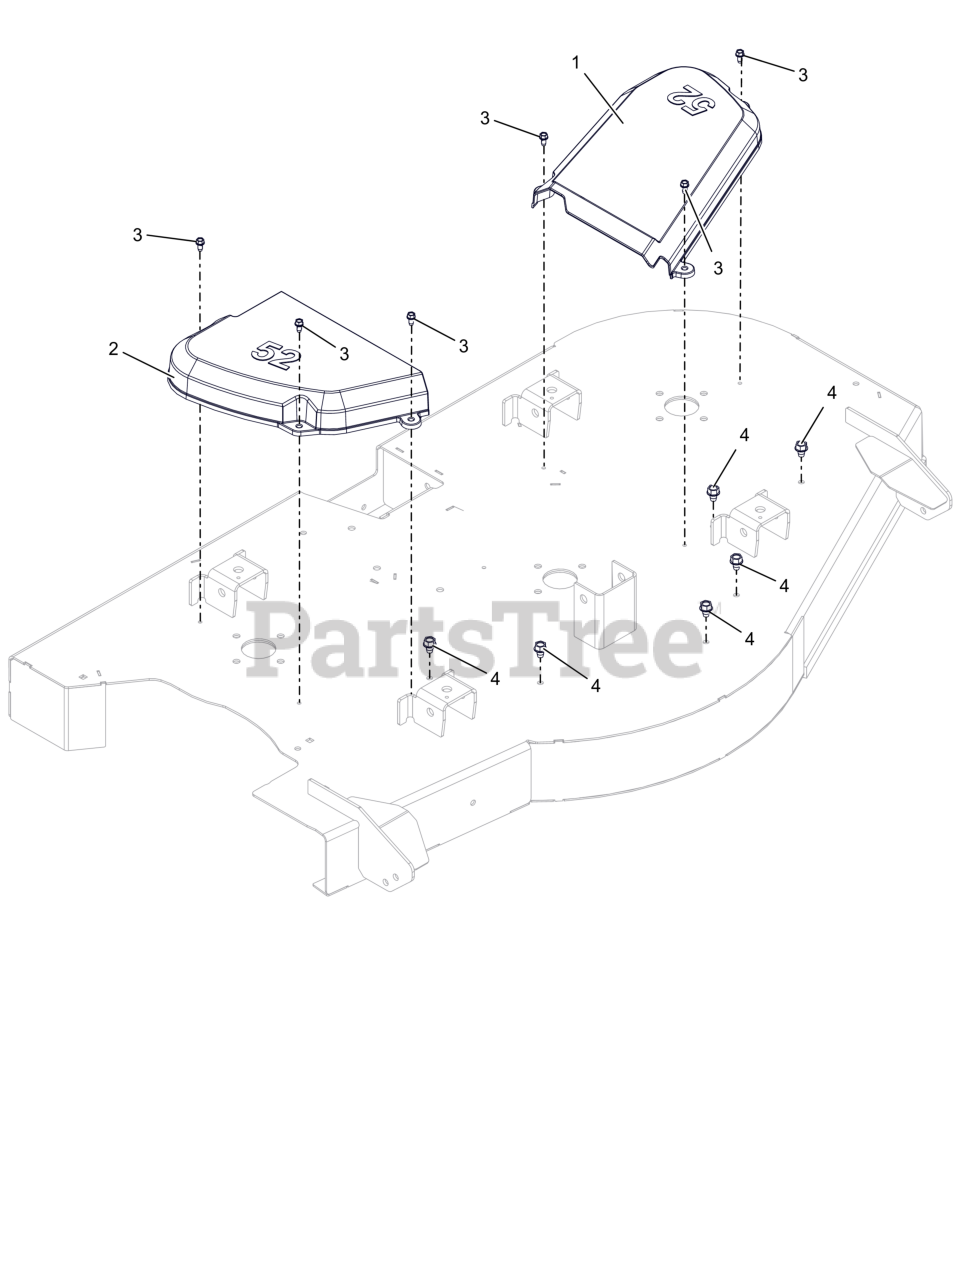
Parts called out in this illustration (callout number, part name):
1	COVER, BELT 52" LH-EDGE
2	COVER, BELT 52" RIGHT-EDGE
3	SCR-TAP .25-20X.50 HWH ZCC
4	SCR,TAP .375-16X.50 HWH TR ZCC
